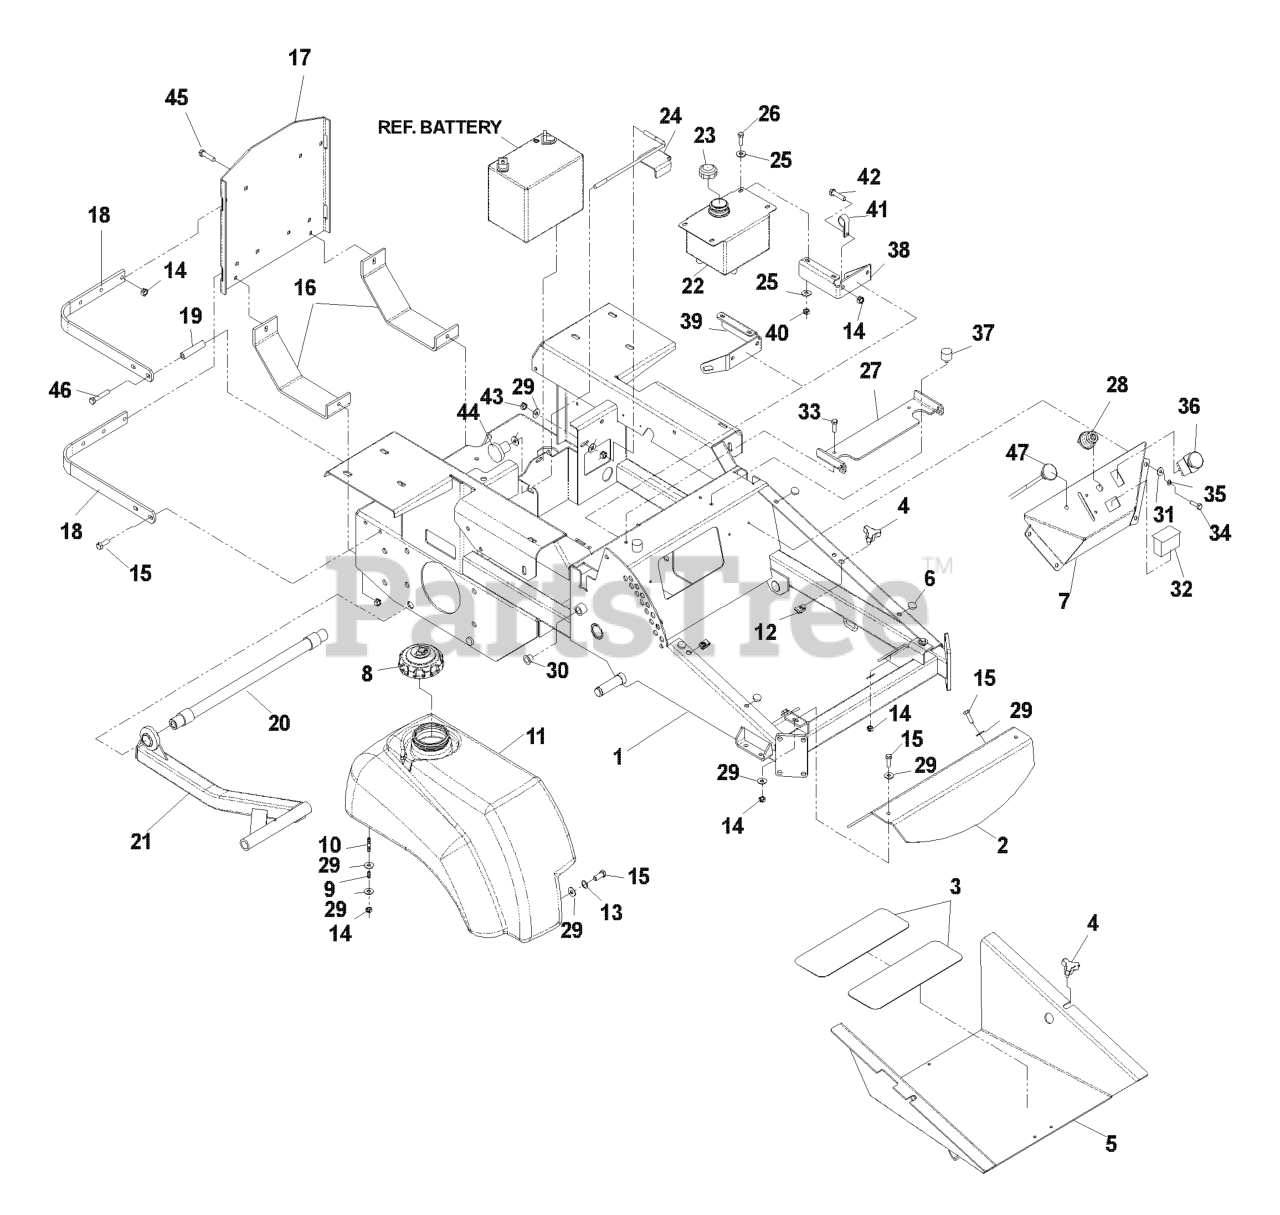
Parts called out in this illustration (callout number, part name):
1	DECK W/DECALS 61" HUS
2	FOOTREST ORANGE
3	ANTI-SKID PAD
4	KNOB W/STUD
5	FOOT PLATE
6	GROMMET, BUMPER
7	CONSOLE WLD
8	FUEL CAP ANTI-SPLASH
10	STUD, 5/16C
11	FUEL TANK RT
12	U-CLIP 5/16-18 NUT RETAINER
13	WASHER.LOCK.HVY.HLCL.SPR.5/16
14	NUT 5/16 NYLOC
15	HCS 5/16C X 1
16	SKID PLATE
17	ENGINE GUARD
18	ENGINE SHROUD BRKT
20	STRUT MOUNT WELDMENT
21	STRUT, RIGHT
23	HYDRAULIC CAP
24	BATTERY HOLD DOWN
25	WASHER 1/4 FLAT
26	HCS 1/4C X 3/4 HCS
27	SEAT BRKT W/DECAL
28	IGNITION SWITCH KIT
29	WASHER 5/16 FLAT
31	WASHER 1/4 FLAT
32	DIGITAL HOUR METER
33	HCS 1/4C X 3/4 HCS
34	SCREW 1/4 X 5/8
35	LOCKWASHER 1/4"
36	RP.SWITCH, BLADE
37	STUD/PLATE MOUNT
38	TANK MOUNT
39	TANK MOUNT
40	NUT.1/4-20.HEX.NYLOC.ZD
42	HCS 5/16C X 3/4
43	NUT 5/16C CENTERLOCK
45	RHSSNB 5/16C X 1.0
46	HCS 5/16C X 4
47	CHOKE CONTROL, COMPLETE
